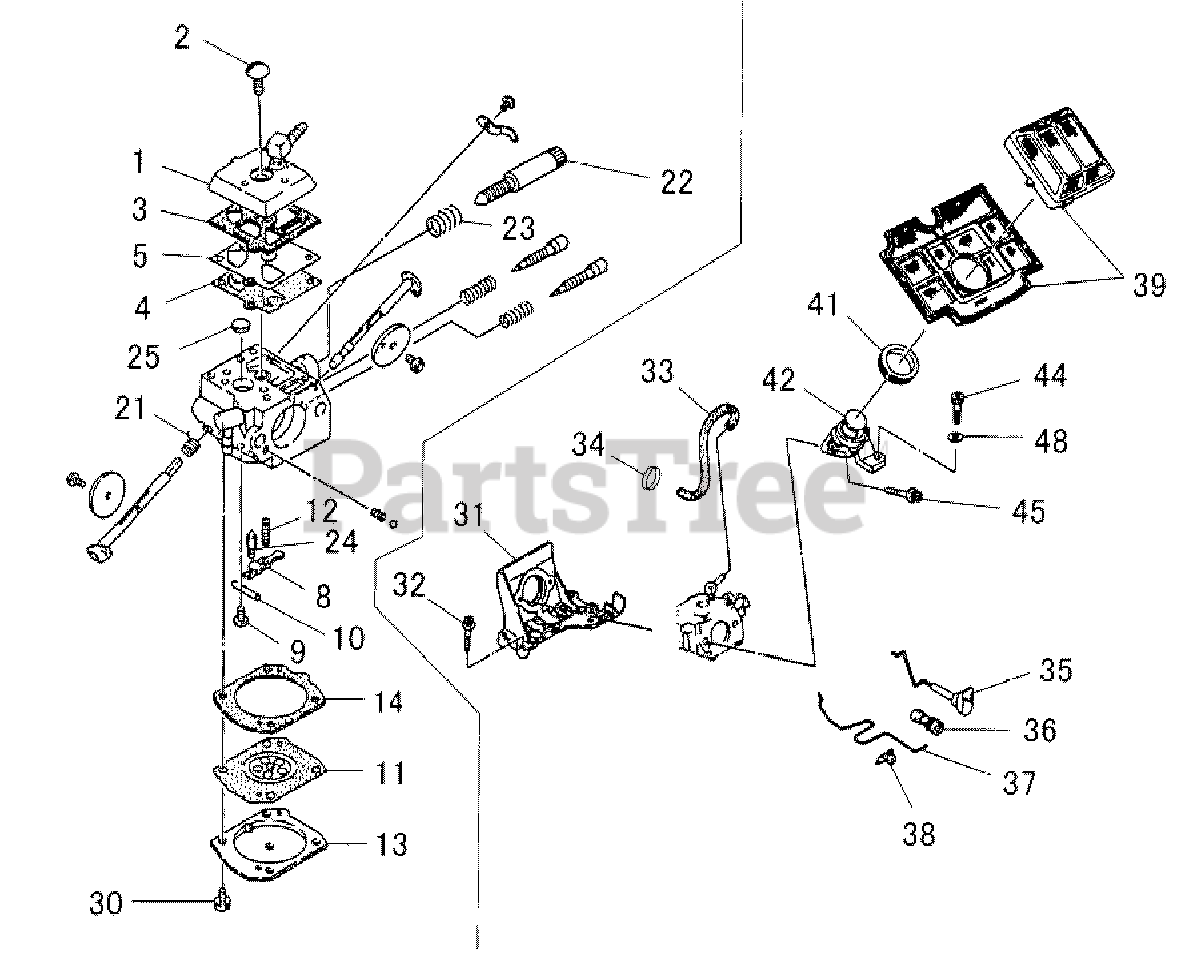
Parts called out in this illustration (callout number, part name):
1	COVER, PUMP
2	SCREW, PUMP COVER
3	GASKET, PUMP
4	DIAPHRAGM, PUMP
5	DIAPHRAGM, PUMP
8	LEVER, METERING
9	SCREW, METERING LEVER PIN
10	PIN, METERING LEVER
11	DIAPHRAGM, METERING
12	SPRING, METERING LEVER
13	COVER, DIAPHRAGM
14	GASKET, METERING
21	SPRING, THROTTLE RETURN
22	SCREW, IDLE ADJUST
23	SPRING
24	VALVE, INLET NEEDLE
25	STRAINER
30	SCREW
31	BRACKET
32	SCREW - 4X16
32	PULSEPIPECOMP
33	PULSE TUBE
34	CLIP
35	ROD, CHOKE
37	ROD, THROTTLE
38	GROMMET
39	AIR CLEANER KIT
41	GROMMET
42	ADAPTOR, INTAKE
44	BOLT - 5X18
45	SCREW - 5X50
48	WASHER - 5
